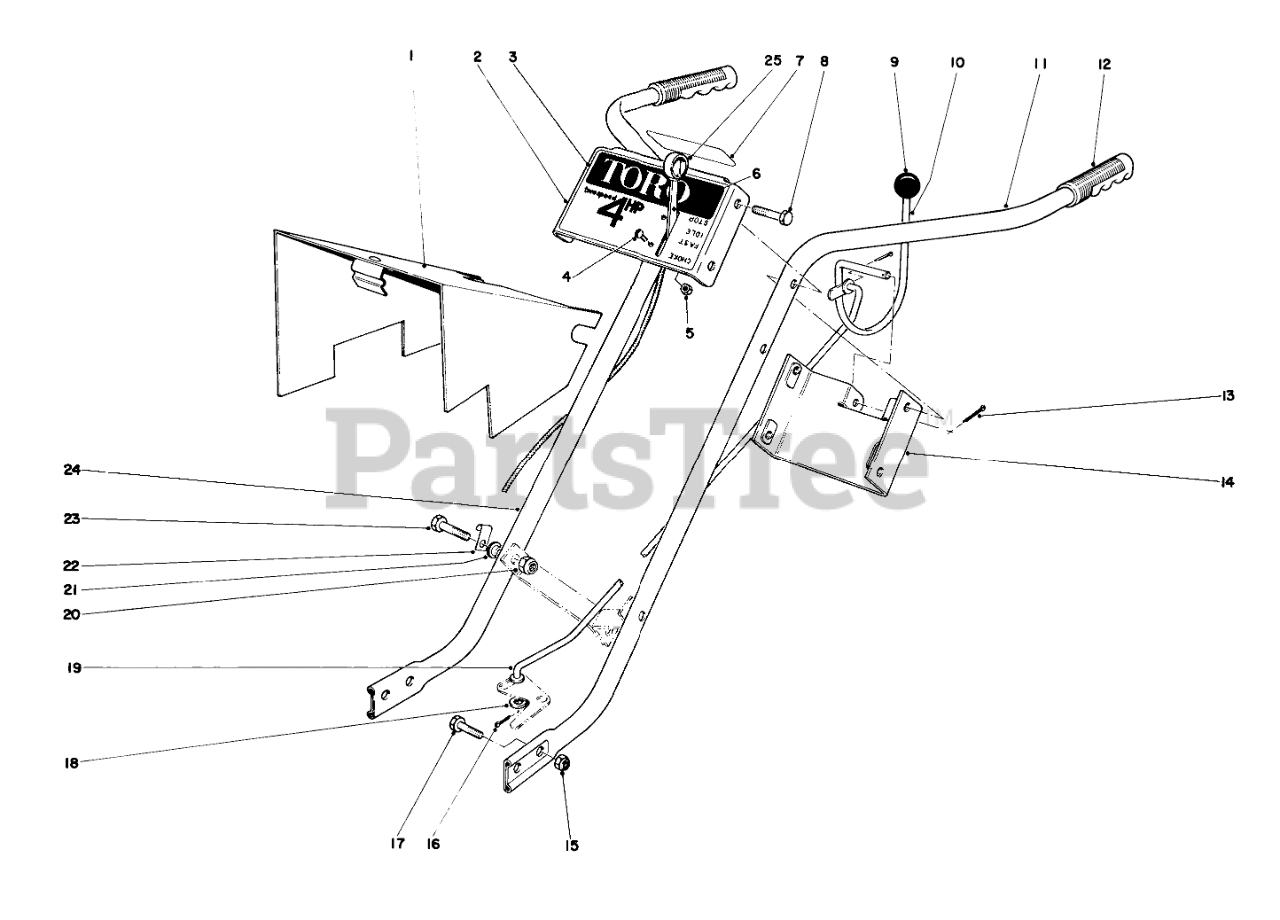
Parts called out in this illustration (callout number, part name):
1	Pulley Cover
2	Control Plate
3	Decal, Control
4	SCREW-PPH
5	NUT-KEPS
6	Throttle Control
7	Decal Clutch
8	SCREW-HH
9	KNOB-CONTROL
10	Clutch Control
11	Handle L.H.
12	Handle Grip
13	PIN-COTTER
14	Handle Brace
15	NUT-LOCK, CONE
16	PIN-COTTER
17	SCREW-HH
18	WASHER-FLAT
19	Clutch Rod
20	NUT-LOCK, CONE
21	Spacer
23	SCREW-HH
24	Handle R.H.
